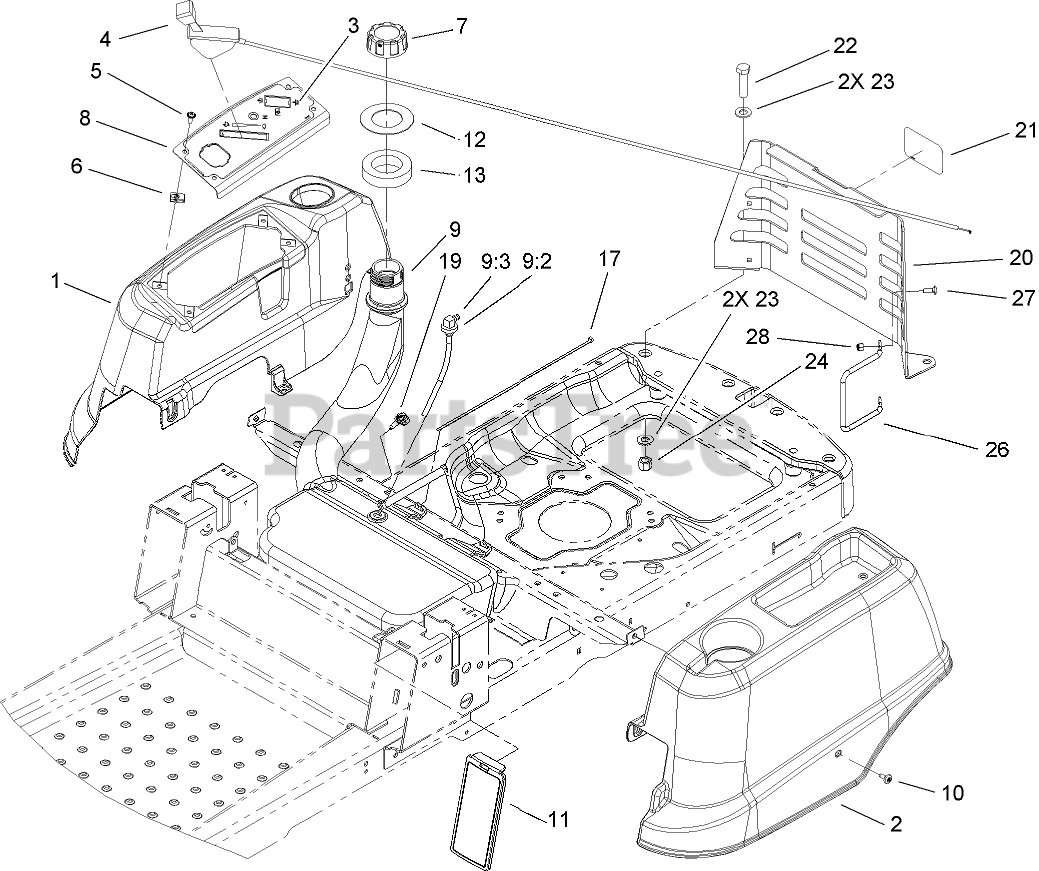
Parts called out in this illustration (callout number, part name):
1	POD-RH
2	POD-LH
3	DECAL-PANEL, CONTROL
4	CABLE-THROTTLE
5	SCREW-PRH
7	CAP-GAS
8	PANEL-CONTROL
9	FUEL TANK ASM
9:2	BUSHING
9:3	FITTING-90 DEGREE
10	SCREW-SHOULDER
11	COVER-CONTROL
12	WASHER-RUBBER
13	SEAL-FOAM
17	TIE-CABLE
19	CLIP-HARNESS
20	SUPPORT-COVER, REAR
21	DECAL
22	SCREW-HH
23	WASHER-FLAT
24	NUT-LOCK, NI
26	GUARD-MUFFLER
27	BOLT-CARR
28	NUT-LOCK, NI
